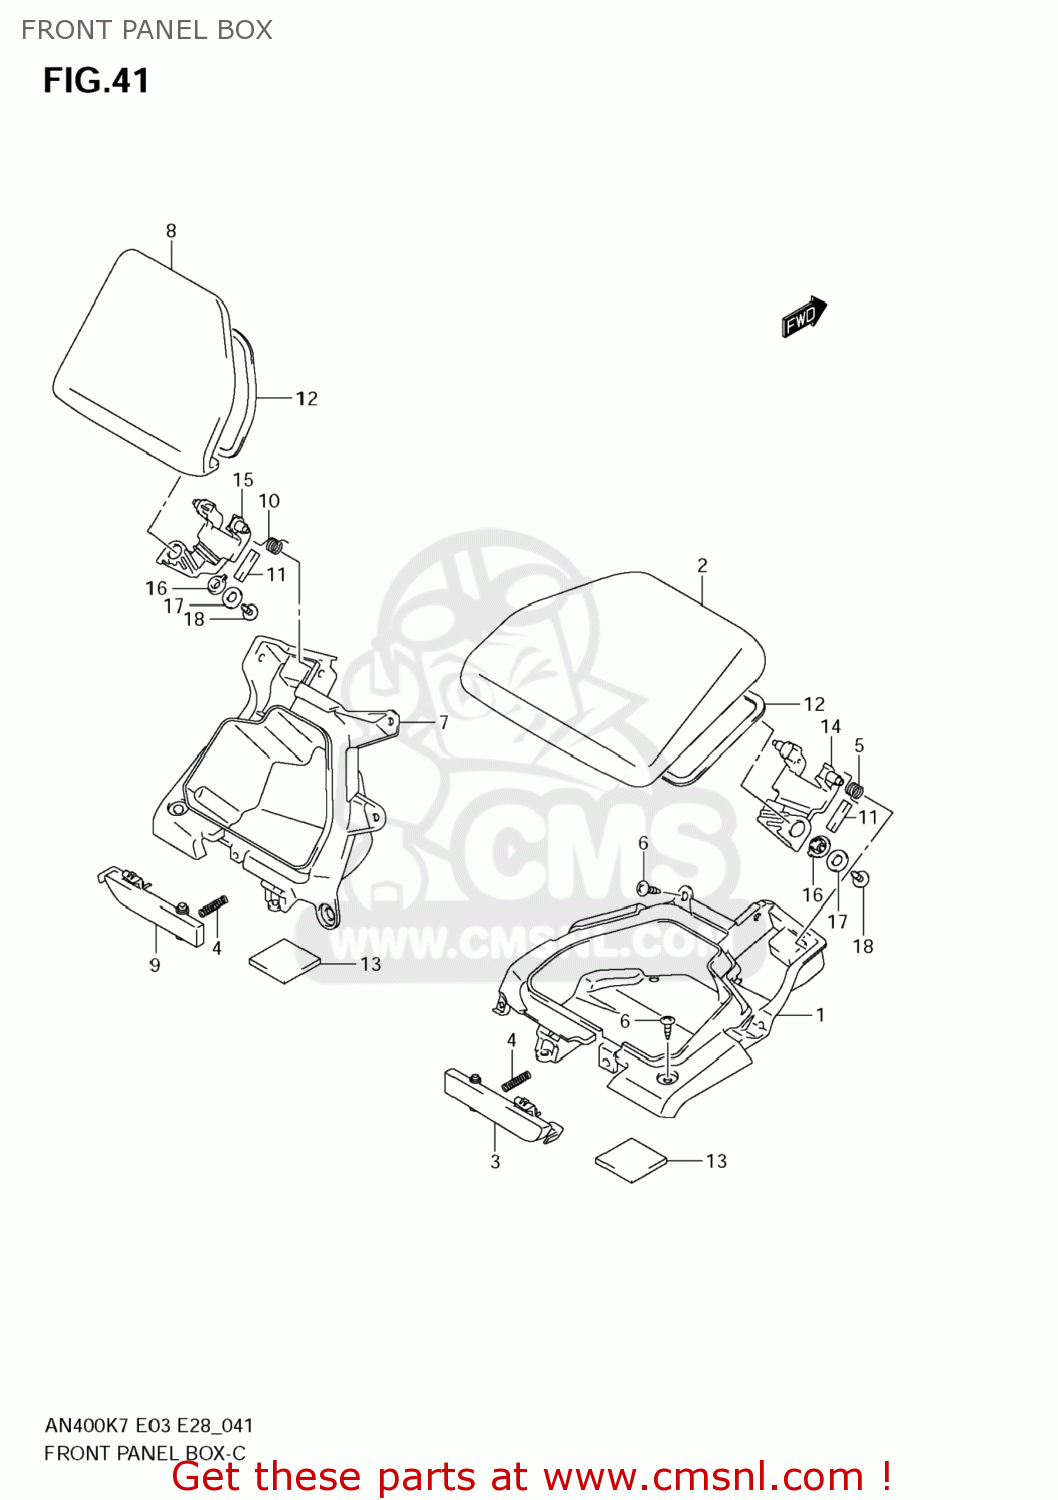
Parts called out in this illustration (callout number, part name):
1	BOX,FRONT PANE
2	LID,FR PANEL,R
3	LOCK,FR PANEL BOX,R
4	SPRING,FRONT P
5	SPRING,FRONT P
6	SCREW
7	BOX,FRONT PANE
8	LID,FR PANEL,L
9	LOCK,FR PANEL BOX,L
10	SPRING,FRONT P
11	CUSHION,FR PANEL LID
12	CUSHION,PANEL BOX NO.2
13	CUSHION,FR PANEL LID NO.2
14	ARM,FR PANEL LID,R
15	ARM,FR PANEL LID,L
16	STOPPER,FR PANEL LID
17	CUSHION
18	SCREW(5X16)
